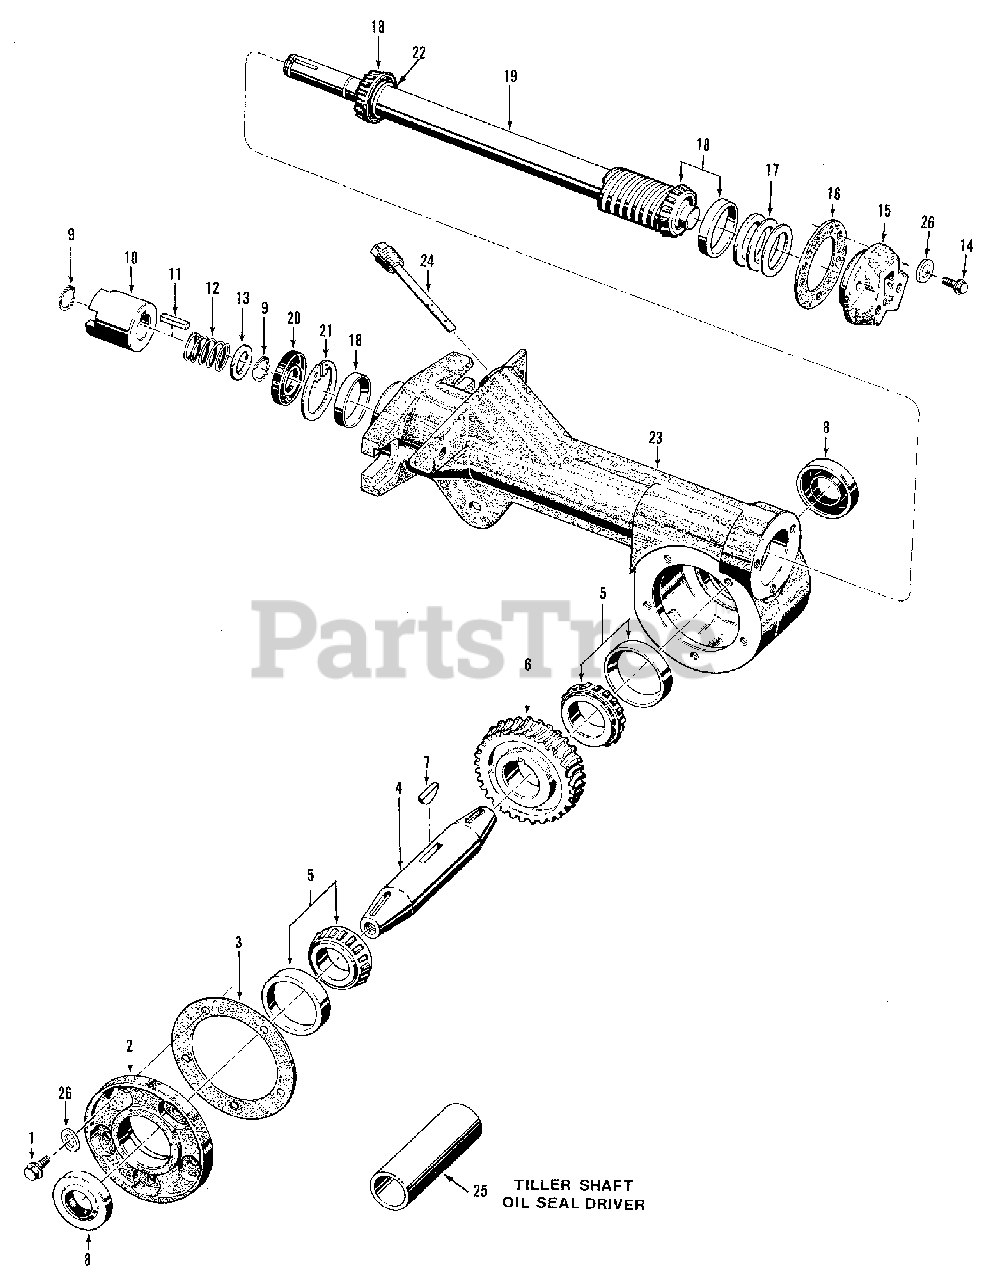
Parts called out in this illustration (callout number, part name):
1	BOLT - hex. hd., 1/4"-20 x 5/8", self-locking flange TILLER TINE SHAFT ASSEMBLY
2	COVER- tiller housing Includes five #9780 bolts (Ref.No.1); TILLER TINE SHAFT ASSEMBLY
3	GASKET- tiller housing cover, .010" thick TILLER TINE SHAFT ASSEMBLY
3	GASKET- same as above, .030" thick TILLER TINE SHAFT ASSEMBLY
4	SHAFT-tiller tine Includes #1104 key(Ref. #7); TILLER TINE SHAFT ASSEMBLY
5	BEARING & CUP - tapered cone roller bearing with cup (race). Cone and cup sold as set only TILLER TINE SHAFT ASSEMBLY
6	WORM GEAR-bronze, tiller tine shaft. Driven by worm on tiller driven shaft TILLER TINE SHAFT ASSEMBLY
6	Kit-Tiller Gear, Cones & Cups. TILLER TINE SHAFT ASSEMBLY
7	KEY - tiller tine shaft. Woodruff key with ends ground TILLER TINE SHAFT ASSEMBLY
8	SEAL-oil, tiller tine shaft Replaces 9616; TILLER TINE SHAFT ASSEMBLY
9	RETAINING RING -(snapring),external. Retains dog clutch to shaft TILLER DRIVE SHAFT ASSEMBLY
10	DOG CLUTCH - tiller drive shaft TILLER DRIVE SHAFT ASSEMBLY
11	KEY-3/16" square X 1",dog clutch to tiller driveshaft TILLER DRIVE SHAFT ASSEMBLY
12	SPRING - dog clutch TILLER DRIVE SHAFT ASSEMBLY
13	SHIM - dog clutch, 1/16" (.062") thick TILLER DRIVE SHAFT ASSEMBLY
14	BOLT - hex. hd., 1/4"-20 x 7/8", self locking flange TILLER DRIVE SHAFT ASSEMBLY
15	CAP -rear bearing TILLER DRIVE SHAFT ASSEMBLY
16	GASKET -rear bearing cap TILLER DRIVE SHAFT ASSEMBLY
17	SHIM - front bearing cap, .010" thick TILLER DRIVE SHAFT ASSEMBLY
17	SHIM - same as above, .030" thick TILLER DRIVE SHAFT ASSEMBLY
17	SHIM - same as above, .005" thick TILLER DRIVE SHAFT ASSEMBLY
17	SHIM - same as above, .062" thick TILLER DRIVE SHAFT ASSEMBLY
18	BEARING & CUP - tapered cone roller bearing with cup (race). Cone and cup sold as set only TILLER DRIVE SHAFT ASSEMBLY
19	SHAFT- main tiller drive ; TILLER DRIVE SHAFT ASSEMBLY
20	SEAL- oil, drive shaft, front TILLER DRIVE SHAFT ASSEMBLY
21	RETAINING RING -(snapring),internal. Retains front bearing cup TILLER DRIVE SHAFT ASSEMBLY
22	WASHER - shoulder (drive shaft) TILLER DRIVE SHAFT ASSEMBLY
23	HOUSING - tiller attachment TRANSMISSION HOUSING AND DIPSTICK
24	DIPSTICK- oil level, tiller attachment TRANSMISSION HOUSING AND DIPSTICK
25	OIL SEAL DRIVER - for tiller shaft oil seals
26	WASHER-1/4",plastic MISCELLANEOUS PARTS
